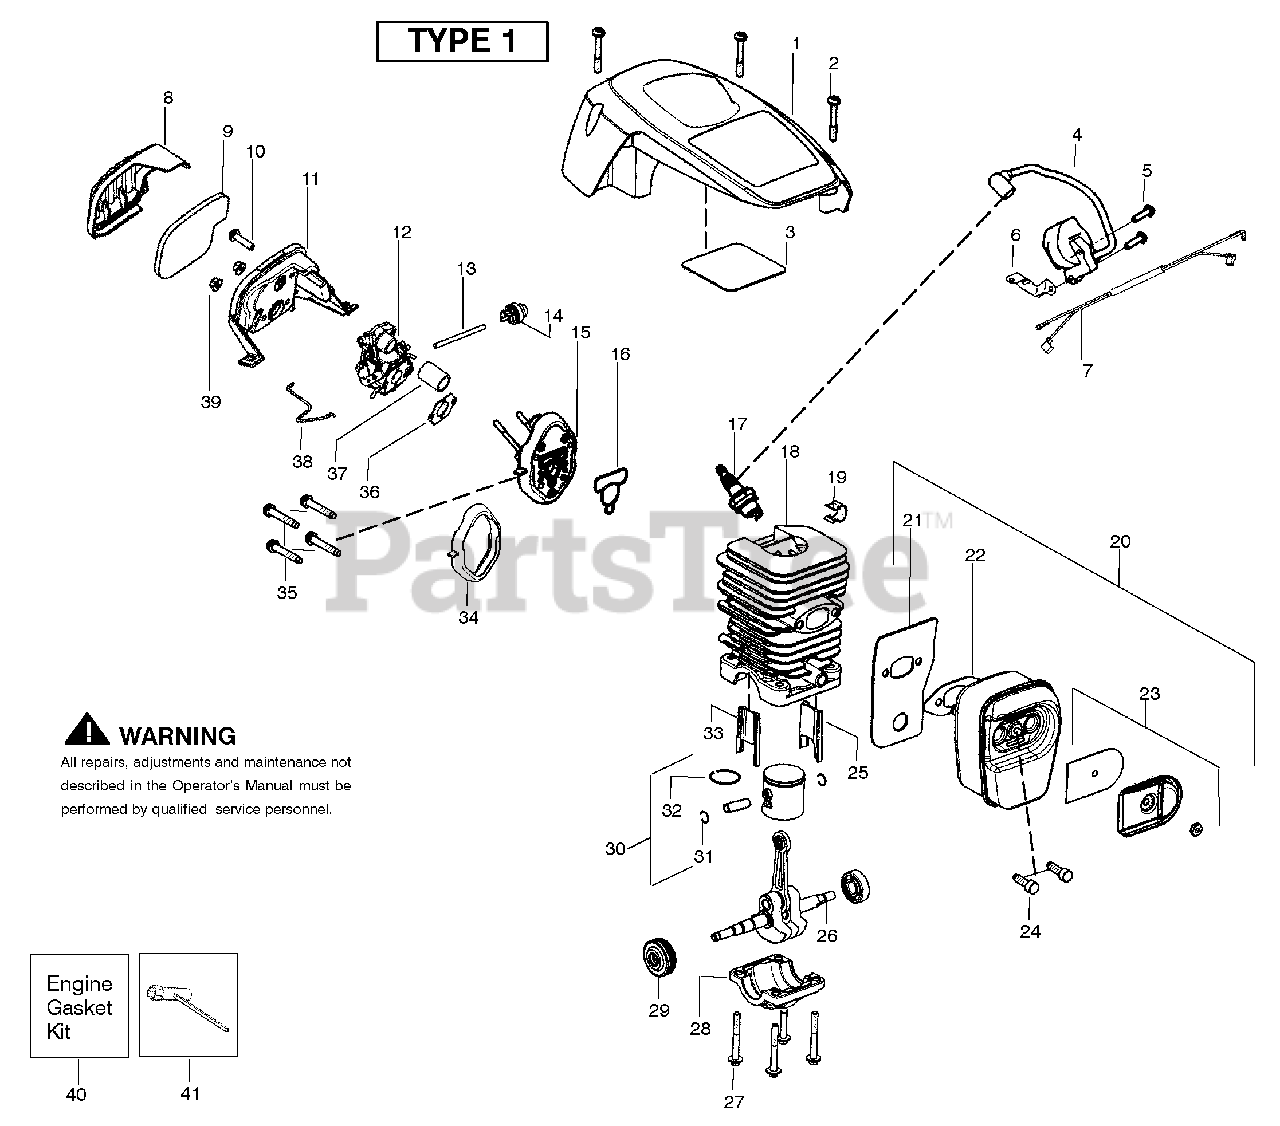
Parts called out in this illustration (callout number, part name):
1	Shield-Cylinder
3	Reflector-Tape
4	Module - Ignition
6	Strap-Ground
7	Assy-Wire Harness
8	Cover-Air Filter
9	Filter-Air
11	Housing-Air Filter
12	Carburetor Zama W-26
12	Carburetor Walbro WTA-30
13	Kit-Fuel Line
14	Bulb-Purge "snap-in"
15	Kit-Carb. Adaptor
16	Gasket-cyl. o-ring
17	Accy-Spark Plug
18	Kit-Cylinder
19	Clip-High Tension Lead
20	Kit-Muffler
21	Backplate-Muffler
22	Gasket-Muffler
23	Kit-Spark Arrestor
24	Bolt-Muffler
25	Insert-Left Cyl.
26	Assy-Crankshaft/Rod
28	Cap-Crankcase
29	Assy-Bearing/Seal
30	Kit-Piston
31	Retainer-Piston Pin
32	Ring-Piston
33	Insert-Right Cyl.
34	Seal-Adaptor
36	Gasket-Carb.
37	Tube-Intake
38	Wire-Throttle
39	Nut-Carb.
40	Kit-Gasket
41	Wrench-Bar
